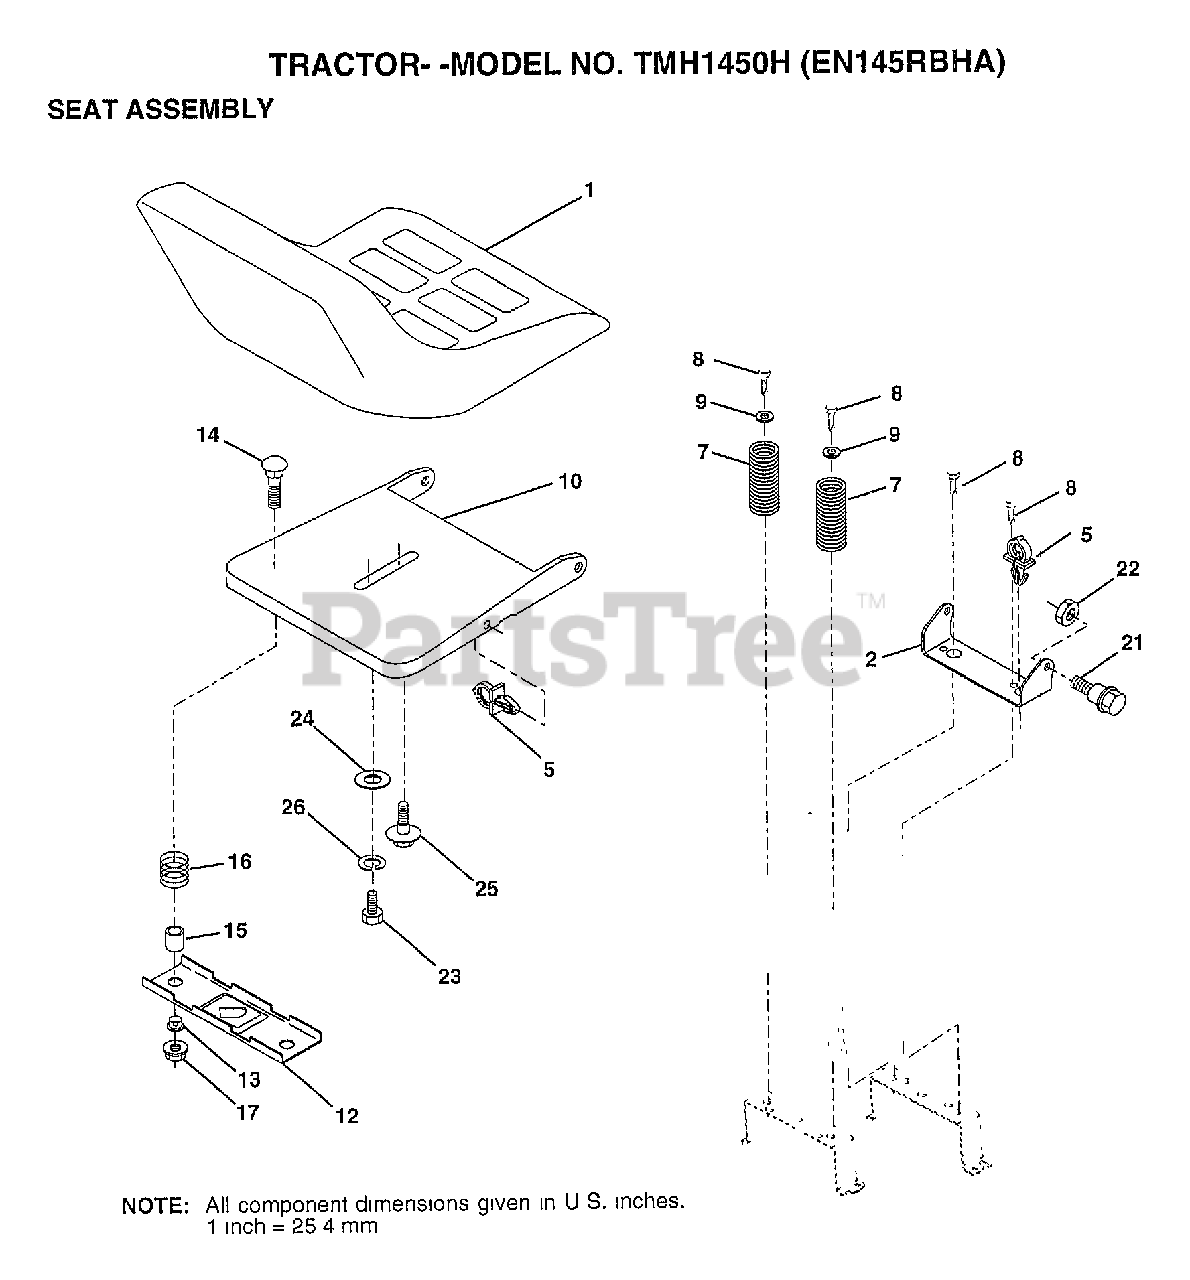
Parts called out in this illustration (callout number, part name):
2	BRACKET PVT SEAT
5	CLIP.PUSH-IN.HING
7	SPRING COMPRESSIO
8	SCREW GTV
9	WASHER
10	PAN-SEAT
12	BRKT SWITCH
13	BUSHING
14	BOLT-RD HD SQ NK
15	SPLIT SPACER
16	SPRING
21	"BOLT,SHOULDER"
22	NUT
23	BOLT
24	WASHER
25	"BOLT,SHOULDER"
26	LOCKWASHER
